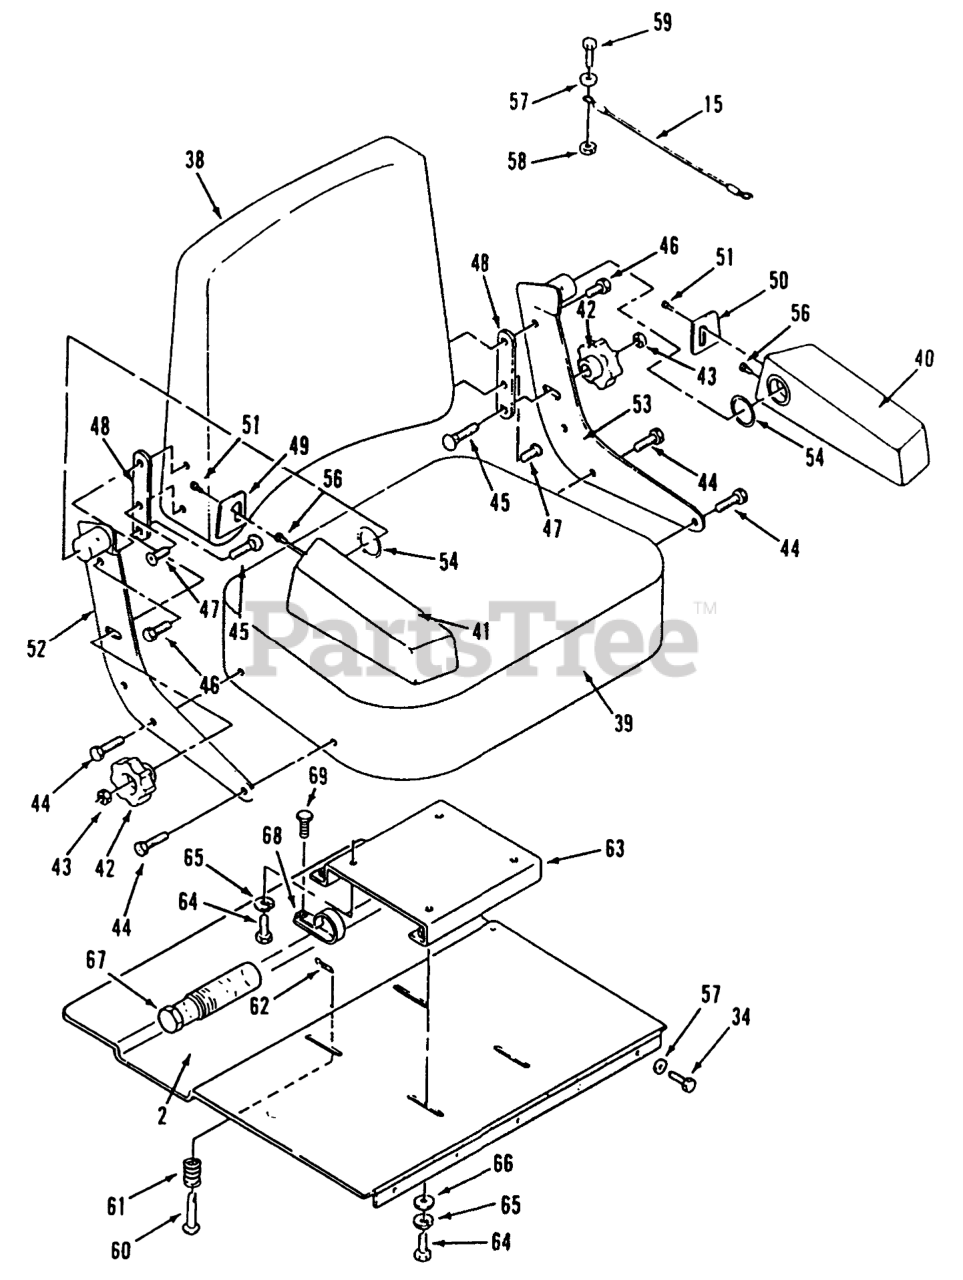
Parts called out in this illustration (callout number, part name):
2	WLDMT-SEAT BRKT B
15	Cable
34	SCREW-HWH
38	SEAT BACK
39	SEAT BOTTOM
40	ARM REST LH
41	ARM REST RH
42	Knob-Lumbar Control
43	KNOB, LUMBAR CONTROL
44	SCREW-HH
45	SCREW-CARR
46	SCREW-HH
47	FLAT HEAD MACH SCREW
48	FRICTION PLATE
49	ARM REST PLATE RH
50	ARM REST PLATE LH
51	SCREW PAN HD 10-16X5
52	RH BACK SUPPORT
53	BACK SUPT LH
54	WASHER
56	SHCS 1/4-20 X 1/2
57	WASHER-FLAT
58	NUT-LOCK, NI
59	SCREW-HH
61	SPRING-COMPRESSION
62	PIN-COTTER
63	ASS'Y-SUPPORT SEA B
64	SCREW-HH
65	WASHER-FLAT
66	WASHER-FLAT
67	TUBE-MANUAL
68	CLAMP-R
69	SCREW-TAPTITE
